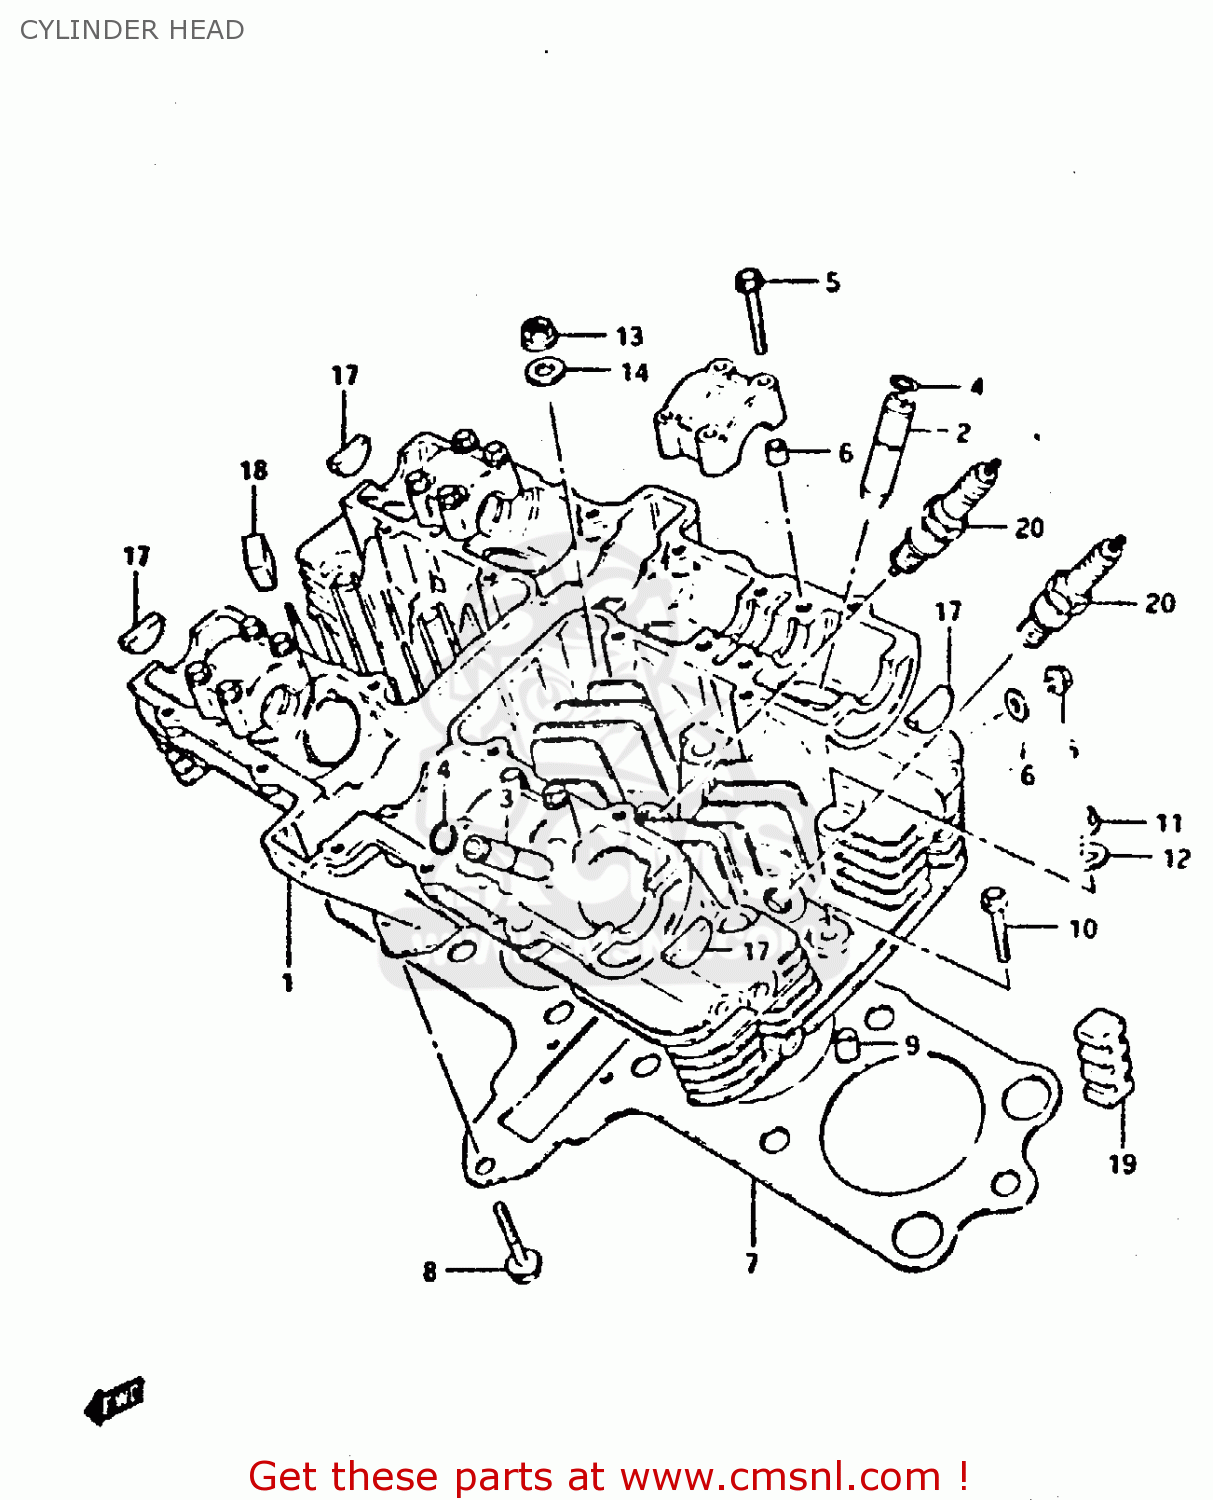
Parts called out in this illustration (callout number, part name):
1	HEAD ASSEMBLY,CYLINDER
2	GUIDE,INTAKE VALVE
3	GUIDE,EXHAUST VALVE
4	RING,SNAP
5	BOLT(6X39)
6	PIN(6.2X8X11)
7	GASKET,CYLINDER HEAD
8	BOLT
9	PIN
10	BOLT,UNDER
11	NUT
12	GASKET 10.5X22X2.0 (NAS)
13	NUT
14	WASHER(10.5X22X2.3)
15	BOLT
16	WASHER
17	PLUG
18	PAD,CYLINDER HEAD
19	PAD,RUBBER N4
20	SPARK PLUG D9EA
